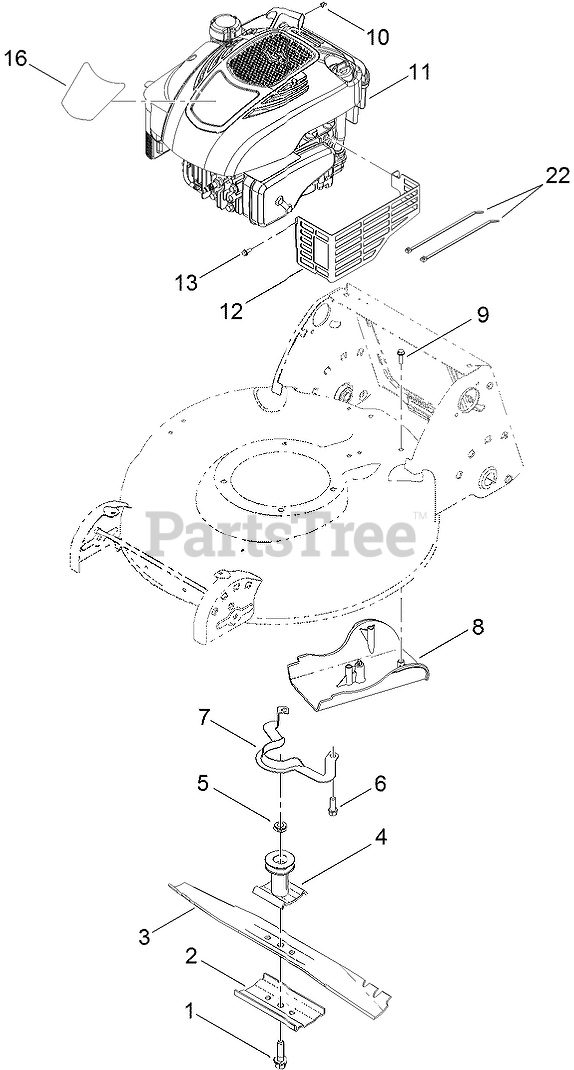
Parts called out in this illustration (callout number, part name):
1	BOLT-BLADE
2	SUPPORT-BLADE
3	BLADE-21 INCH
4	DRIVER-BLADE
5	Spacer-Driver
6	SCREW-TAPTITE
7	Guide-Belt
8	COVER-BELT
9	SCREW-HWH
10	STOP-ROPE
12	SHIELD-MUFFLER
13	SCREW-TAPTITE
16	DECAL-SHROUD
22	TIE-CABLE
